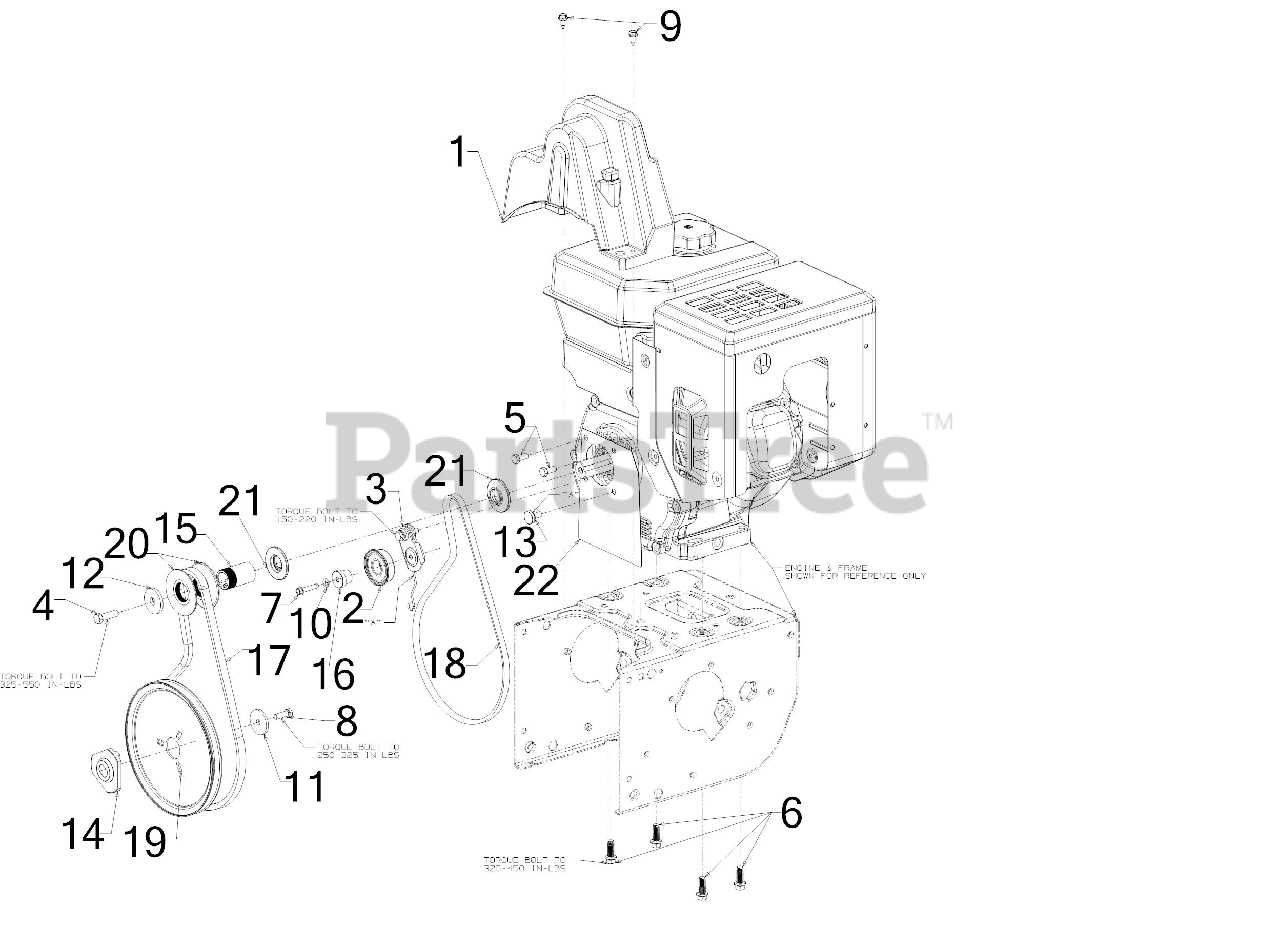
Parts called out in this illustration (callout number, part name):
1	BELT COVER (LARGE BLOCK)
2	IDLER PULLEY ASSEMBLY
3	IDLER ASSEMBLY
4	SCREW 3/8-24X1.25
5	SCREW 5/16-24 x .750 GR5
6	SCREW 3/8-16 x 1
7	SCREW 1/4-20 x 1.25
8	SCREW 5/16-24 x .875 GR5
9	SCREW 1/4-20X.625
10	LOCK WASHER
11	FLAT WASHER
12	FLAT WASHER .45 x 1.5 x .172 HT
13	SHOULDER SCREW
14	ADAPTER PULLEY .75 DIA W/DD
15	PULLEY SPACER
16	SHOULDER SPACER
17	BELT-.500 x 37
18	V-BELT 3/8 x 35.68"
19	AUGER PULLEY
20	HALF PULLEY 4L V x 2.6 OD
21	HALF PULLEY-3/8 V x 1.7160
22	ENGINE PLATE (FRONT COVER)
